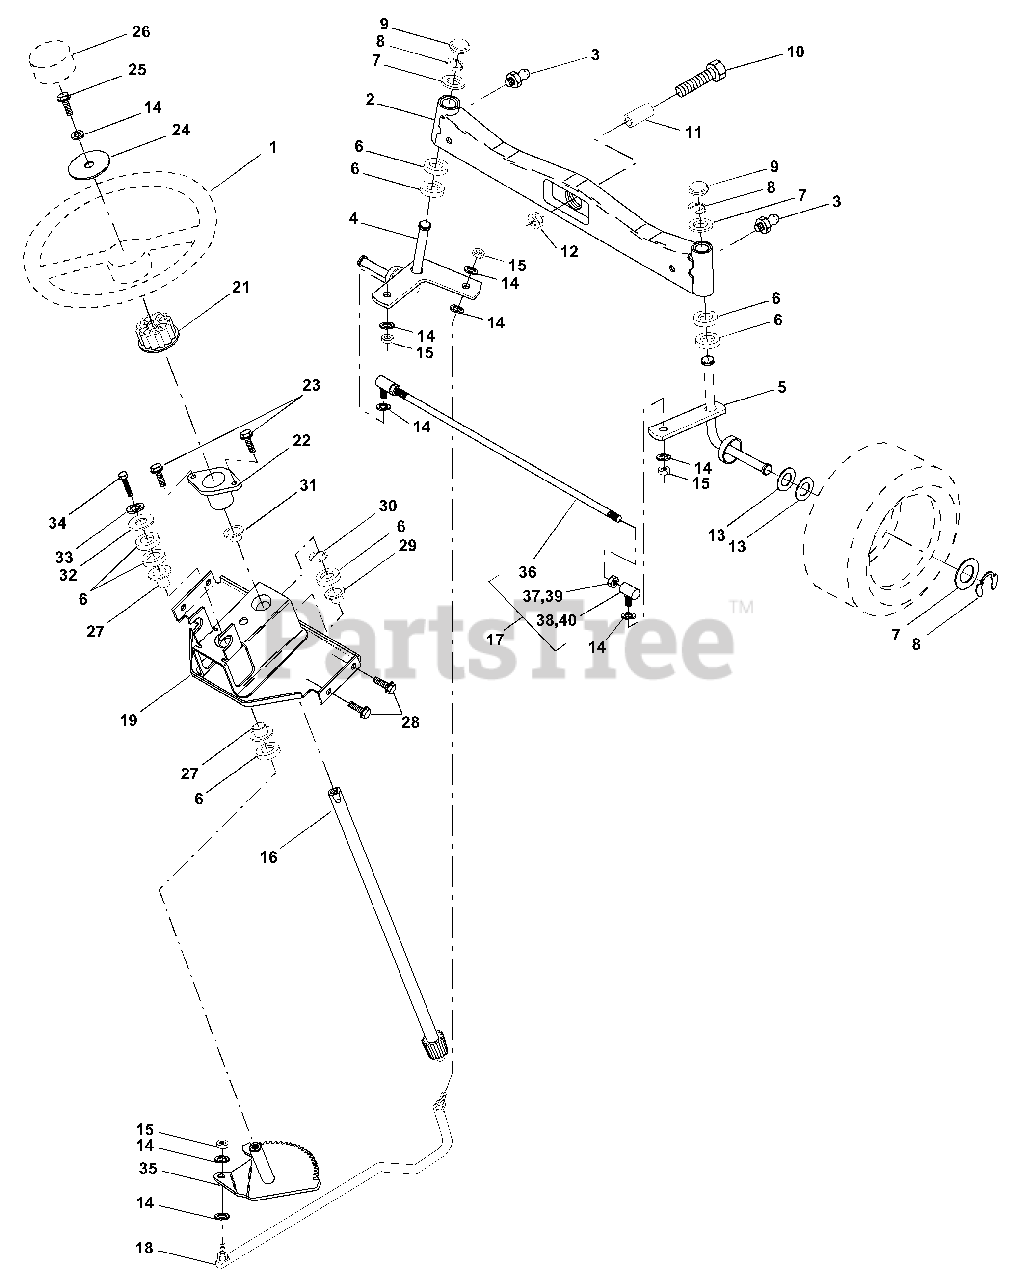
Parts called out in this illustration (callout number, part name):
1	Wheel, Steering
2	Axle Asm., Front
3	Fitting, Grease
4	Spindle Asm, LH
5	Spindle Asm., RH
6	Bearing, Race Thrust Harden
7	Washer 25/32 x 1-5/8 x 16 Ga.
8	Ring, Klip #T5304-75
9	Cap, Spindle
10	Bolt, Fin Hex 5/8-11 x 2-3/4
11	Spacer, Brg. Axle Front
12	Nut, Lock Flange 5/8-11 Unc
13	Washer 25/32 x 1-1/4 x 16 Ga.
14	Washer, Lock Hvy Hlcl Spr 3/8
15	Nut, Fin Hex 3/8-24 Unf
16	Shaft Asm., Steering
17	Rod Asm., Tie Ball J Ball Vgt
18	Draglink, Ball Joint Solid Vgt
19	Support Asm., Steering Vgt
21	Adapter, Wheel Steering
22	Bushing, Strg. Blk
23	Screw, Slftp #10-16 x 1/2 Ty-b
24	Washer 13/32 x 2-3/8 x 8 Ga.
25	Bolt, Fin Hex 3/8-16 x 1 Gr. 5
26	Cap , Wheel Steering
27	Bearing, Col. Strg.
28	Screw Thdrol 3/8-16 x 3/4
29	Bearing, Flange
30	Ring, Klip Truarc #5304-75
31	Bushing, Nyliner Snap
32	Washer 11/32 x 1 x 10 Ga.
33	Washer, Lock Hvy Hlcl Spr 5/16
34	Bolt, Hex Hd 5/16-18 x 3/4
35	Gear, Sector Steering
36	Tie Rod
37	Jam Nut RH Thread
38	Joint Asm. Ball RH Thread
39	Jam Nut
40	Joint Asm. Ball LH Thread
